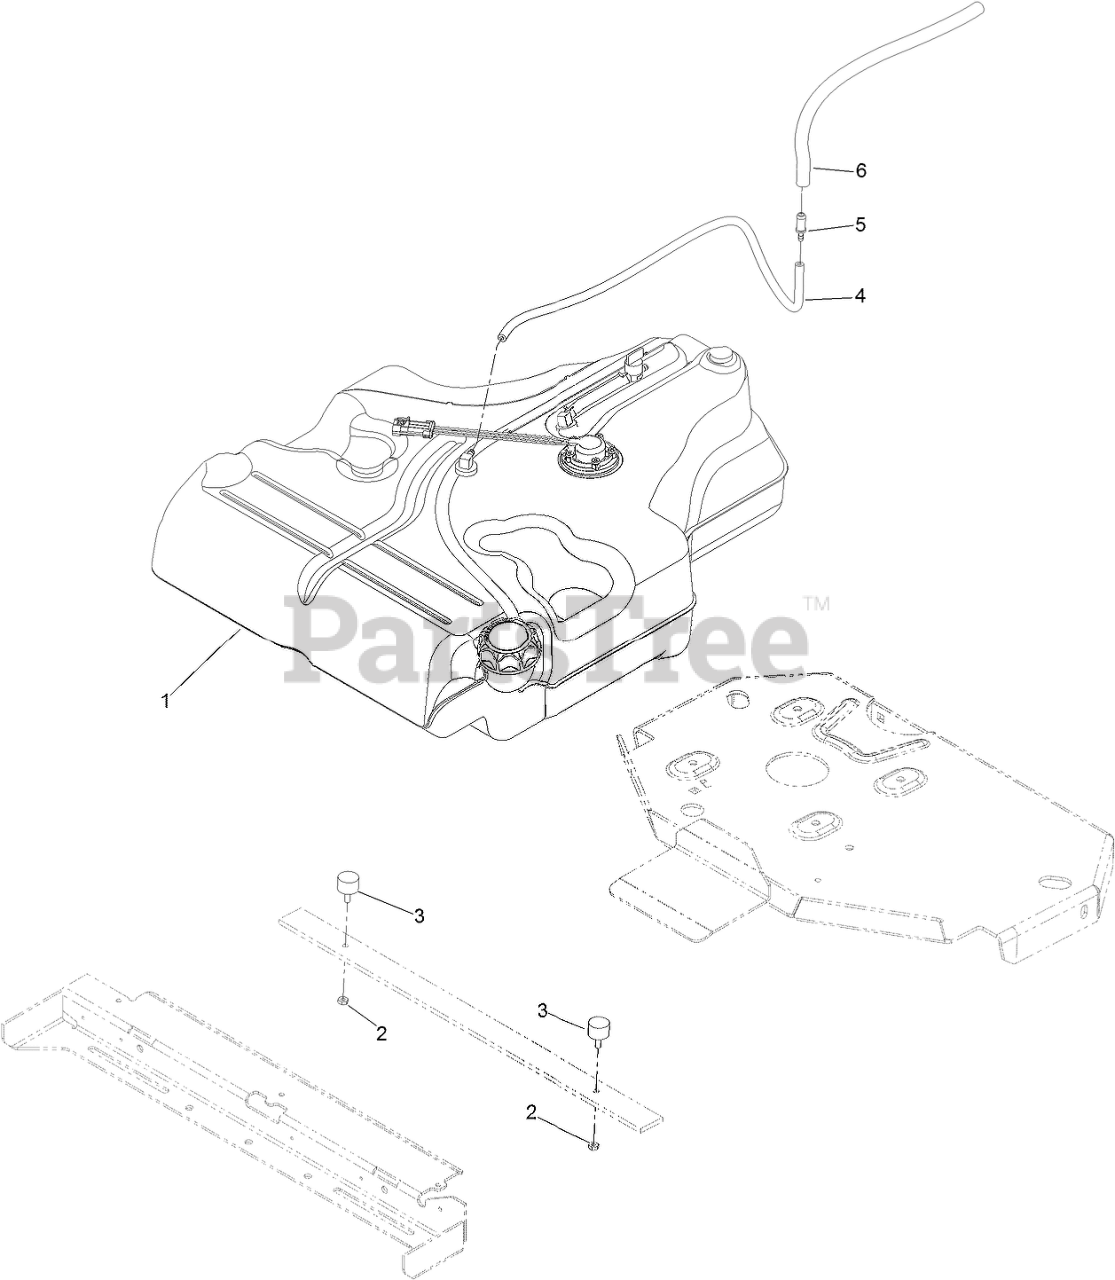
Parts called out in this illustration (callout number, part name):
1	FUEL TANK ASM
2	NUT-JAM
4	HOSE-FUEL
5	FITTING-STRAIGHT
6	HOSE-FUEL
